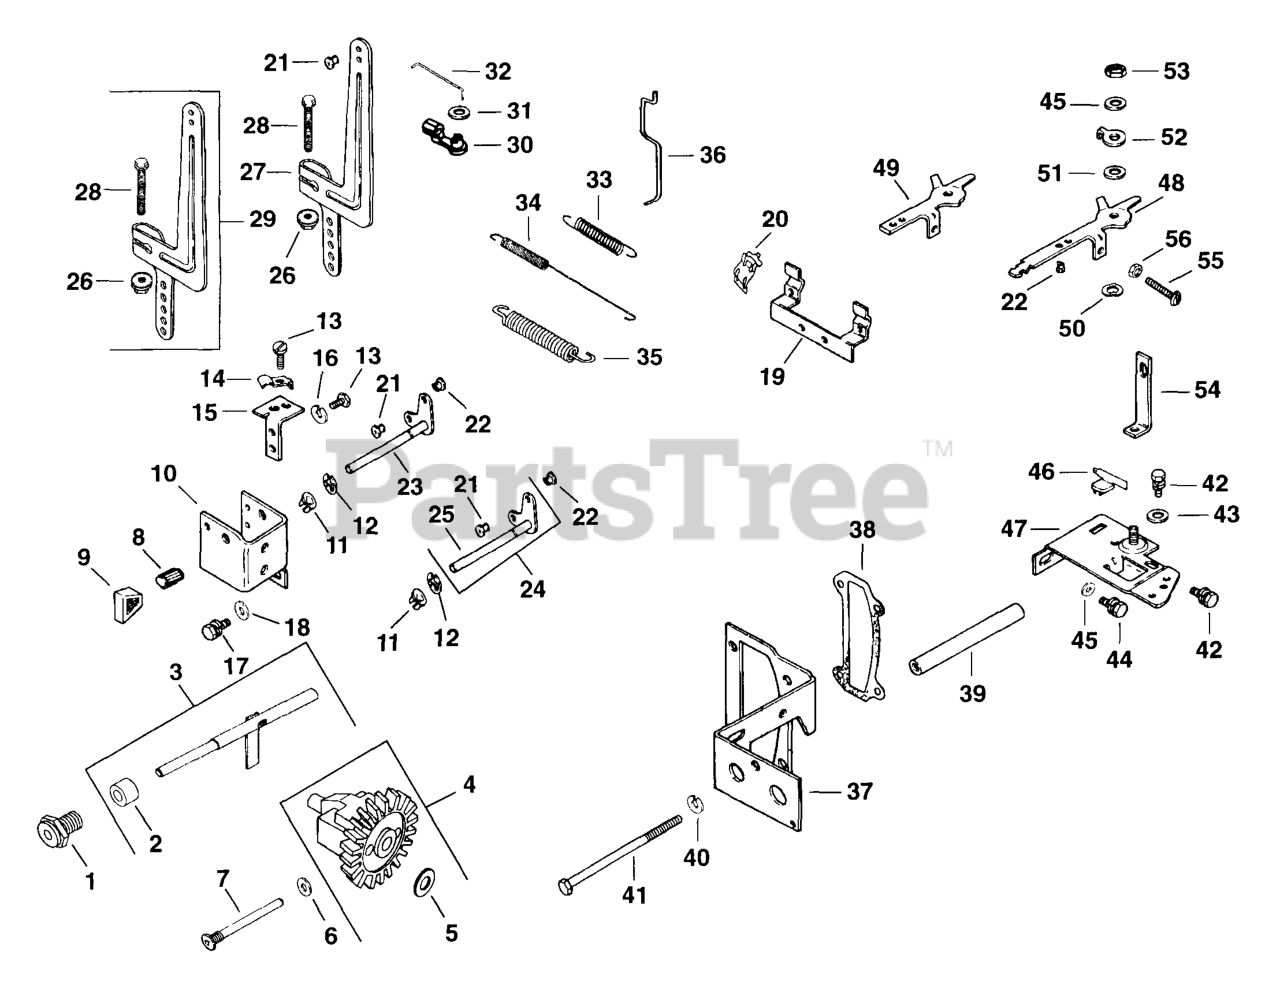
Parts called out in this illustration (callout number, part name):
1	BUSHING
2	SPACER USE 25 112 17-S
3	KIT, SHAFT
4	KIT, GOVERNOR GEAR
8	KNOB
8	KNOB - DISCONTINUED
9	KNOB - DISCONTINUED
10	BRACKET - DISCONTINUED
11	BUSHING - DISCONTINUED
13	SCREW, WSH HD TAP #10-24X13/32" USE 25 086 109-S
13	SCREW, IND SLT HD 10-24X3/8" USE 25 086 79-S
14	CLAMP
15	BRACKET - DISCONTINUED
16	WASHER, SPRING LOCK #10
17	SCREW DISCONTINUED
18	WASHER - USE X-25-92
19	BRACKET - DISCONTINUED
20	CLIP
21	BUSHING, THROTTLE LINKAGE
22	BUSHING-DISCONTINUED
23	KIT LEVER - USE 47 755 41
23	KIT, LEVER - DISCONTINUED
24	SHAFT, CHOKE CONTROL ASSY - DISCONTINUED
25	SHAFT, CHOKE
26	PALNUT, 1/4-20
31	WASHER
36	LINKAGE, CHOKE - DISCONTINUED
36	LINKAGE, CHOKE
37	BRACKET - DISCONTINUED
38	GASKET, CAMSHAFT COVER
39	SPACER - DISCONTINUED
40	WASHER, SPRING LOCK 1/4"
41	SCREW - DISCONTINUED
42	SCREW
43	WASHER, FLAT 1/4" (O.D. 1/2")
44	SCREW, SEMS 1/4-20X5/8" USE 25 086 539-S
45	WASHER, FLAT 1/4" (O.D. 5/8")
47	BRACKET - DISCONTINUED
48	LEVER (KM)
50	WASHER, SPRING 1/4"
51	WASHER, PLAIN 1/4"
53	NUT, LOCK 1/4-20
54	BRACKET - DISCONTINUED
55	SCREW, SLT PAN HD 10-24X1" USE 25 086 65-S
55	SCREW, SKT SET #10-24X1" - DISCONTINUED
56	NUT, MACH SCREW #10-24 GRD 2 USE 25 100 17-S
